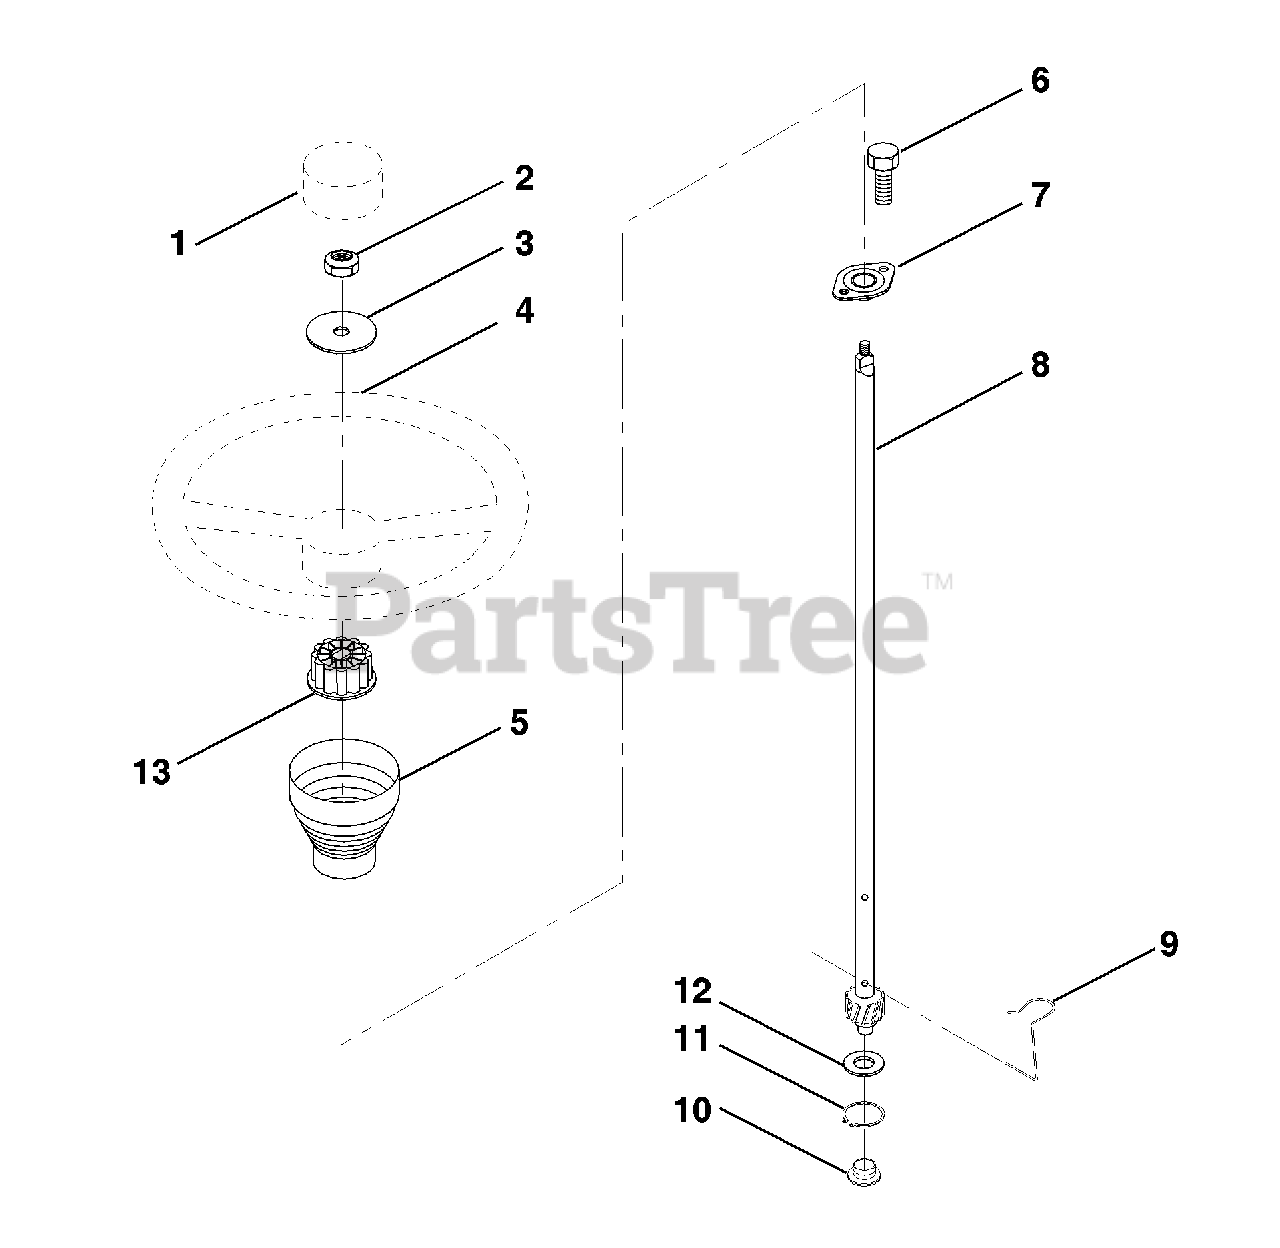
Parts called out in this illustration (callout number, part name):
1	Insert, Steering Wheel
2	Locknut 3/8-24 UNF
3	Washer 12/32 x 2-3/8 x 8 Gauge
4	Steering Wheel
5	Sleeve, Steering
6	Screw, Hex Head #10-16 x 1/2
7	Bushing, Steering
8	Shaft, Steering
9	Clip, Steering
10	Bushing, Lower, Steering
11	Ring, Retaining
12	Washer 21/32 x 1 x 16 Gauge
13	Adaptor, Steering Wheel
